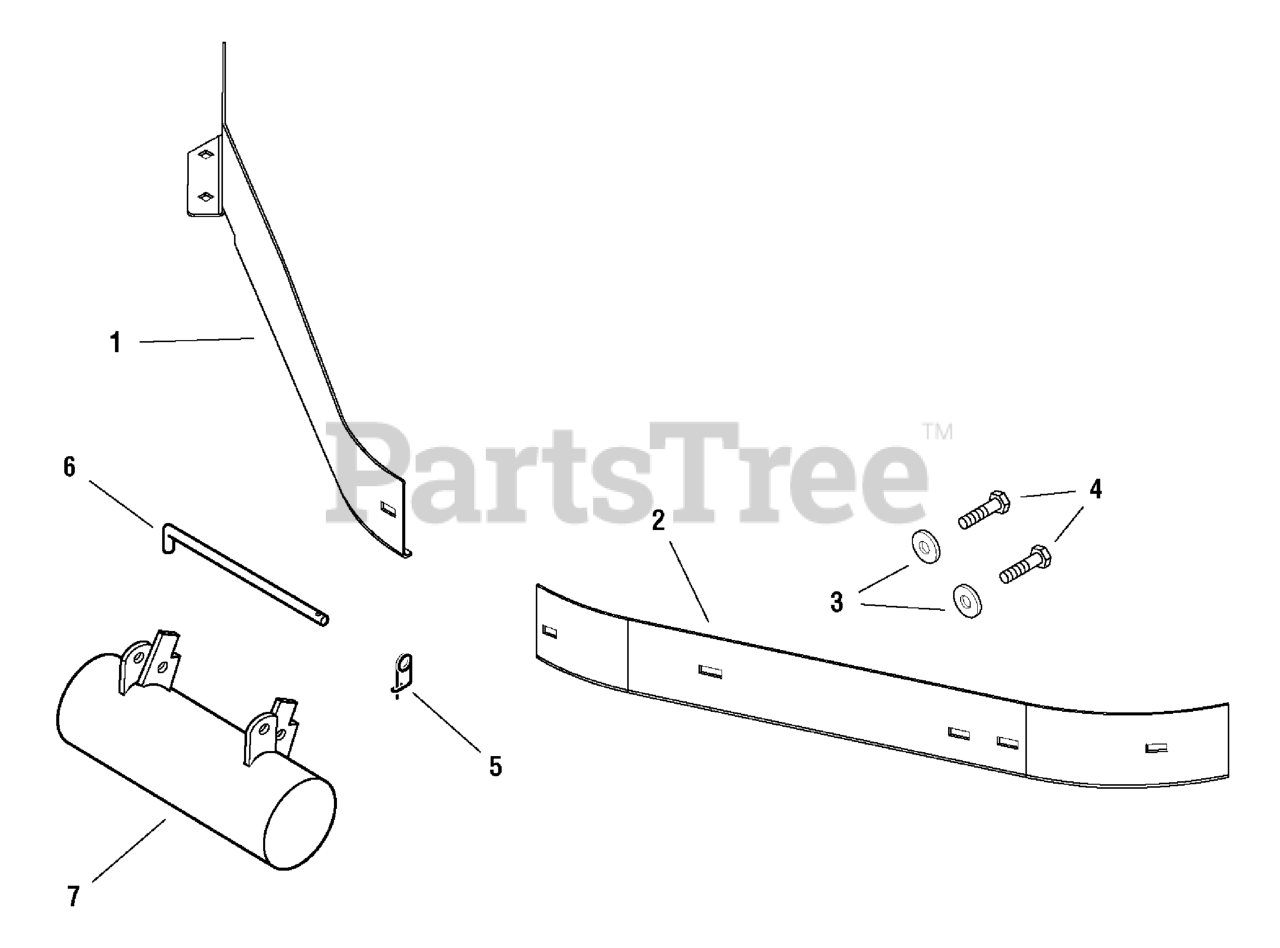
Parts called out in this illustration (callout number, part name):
1	Baffle, RH 44" Anti-blow Out
2	Baffle, LH 44" Anti-blow Out
3	Washer, 1/4" Thick, for Bag Hitch Installation
4	CAPSCREW, Hex, 3/8-16 x 1-3/8
5	Safety Clip
